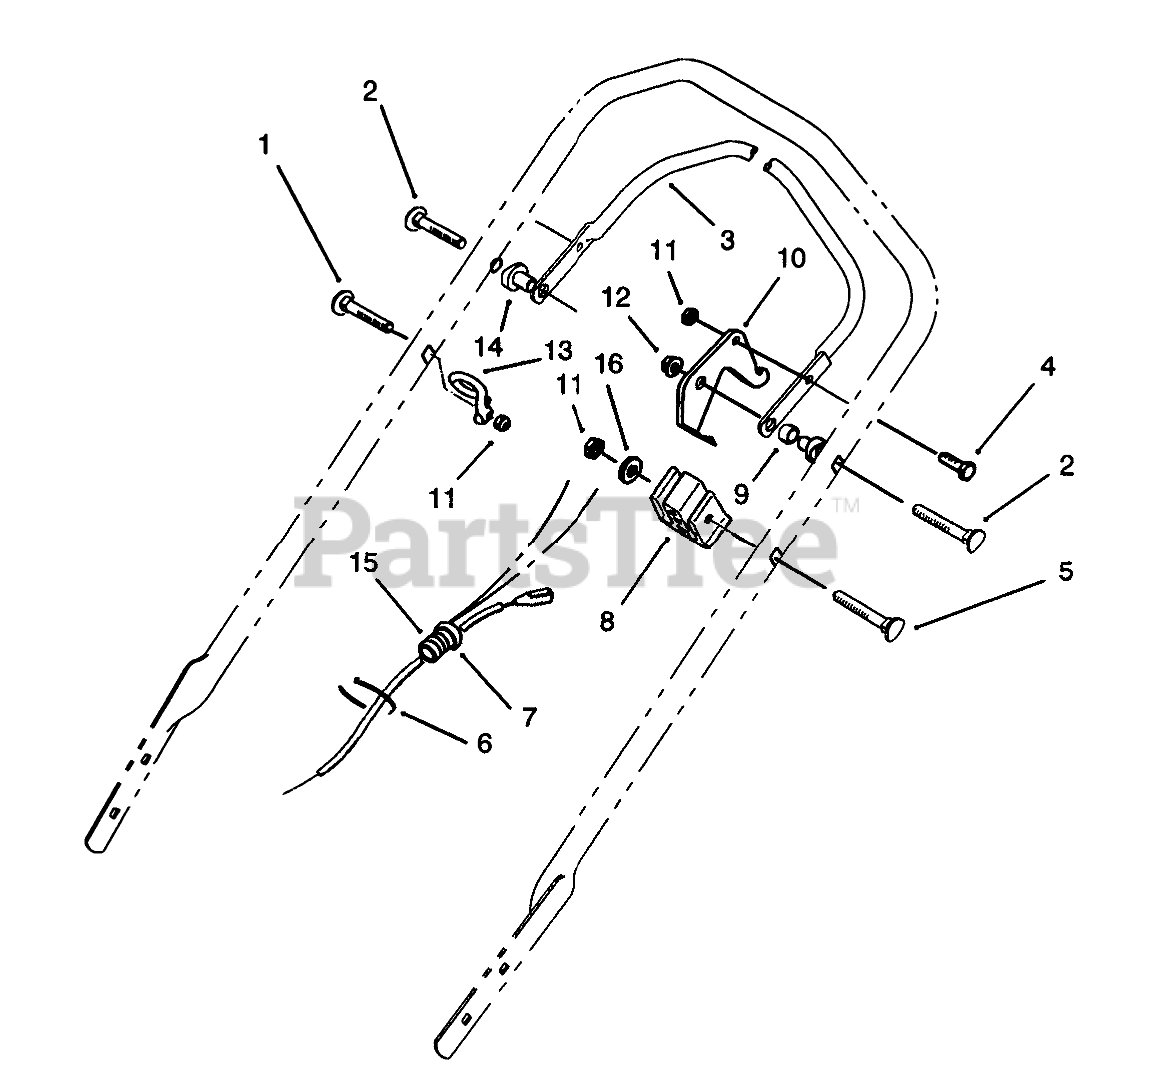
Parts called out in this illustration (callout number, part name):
1	HANDLE SCREW
2	5/16-18 X 2 HNDLE SCREW
3	Bar-Control
4	SCREW-HH
5	HANDLE SCREW
6	TIE-CABLE
7	FITTING-RING
8	SUPPORT-CABLE
9	SPACER-NYLON
10	LEVER-CONTROL
11	NUT-LOCK, NI
12	NUT-LOCK, NI
13	Guide
14	SPACER-SUPPORT
15	CONT. CABLE COVER
16	WASHER-FLAT
